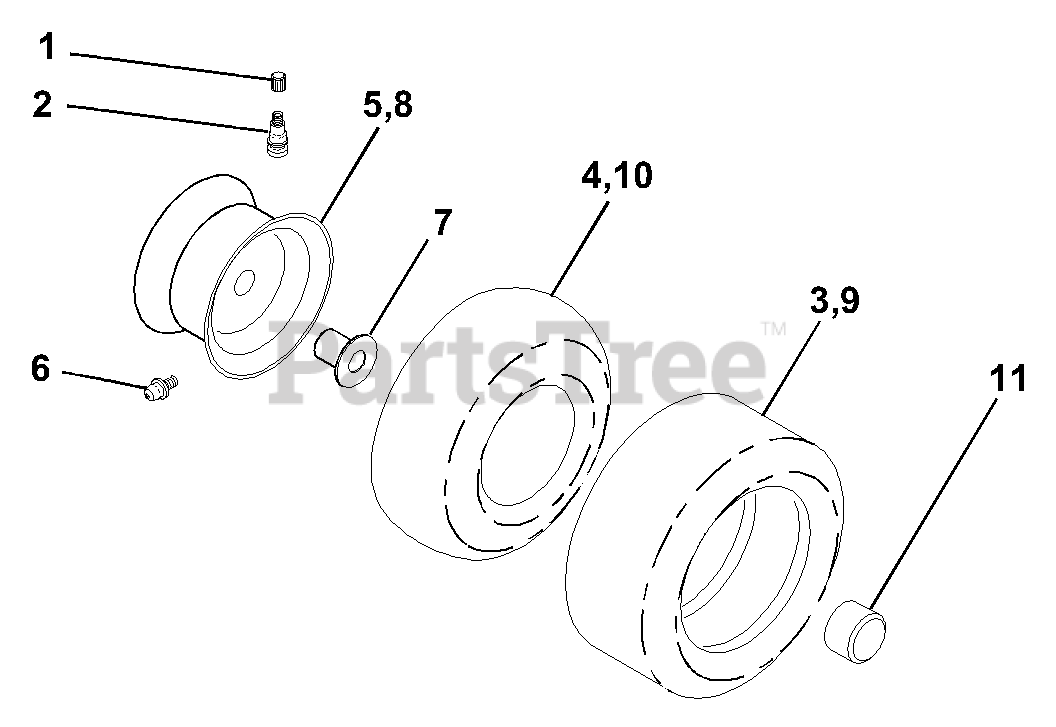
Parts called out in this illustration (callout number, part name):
1	Cap Valve Tire
2	Stem Valve
3	Tire F Ts 15 X 6 0 - 6 Service
4	Tube Front
5	Rim Asm 6"
6	Fitting Grease
7	Bearing Flange
8	Rim Asm 8" rear White Service)
9	Tire R Ts 20 x 10 C Service
10	Tube Rear
11	Cap Axle Blk 1 50 X 1 00
